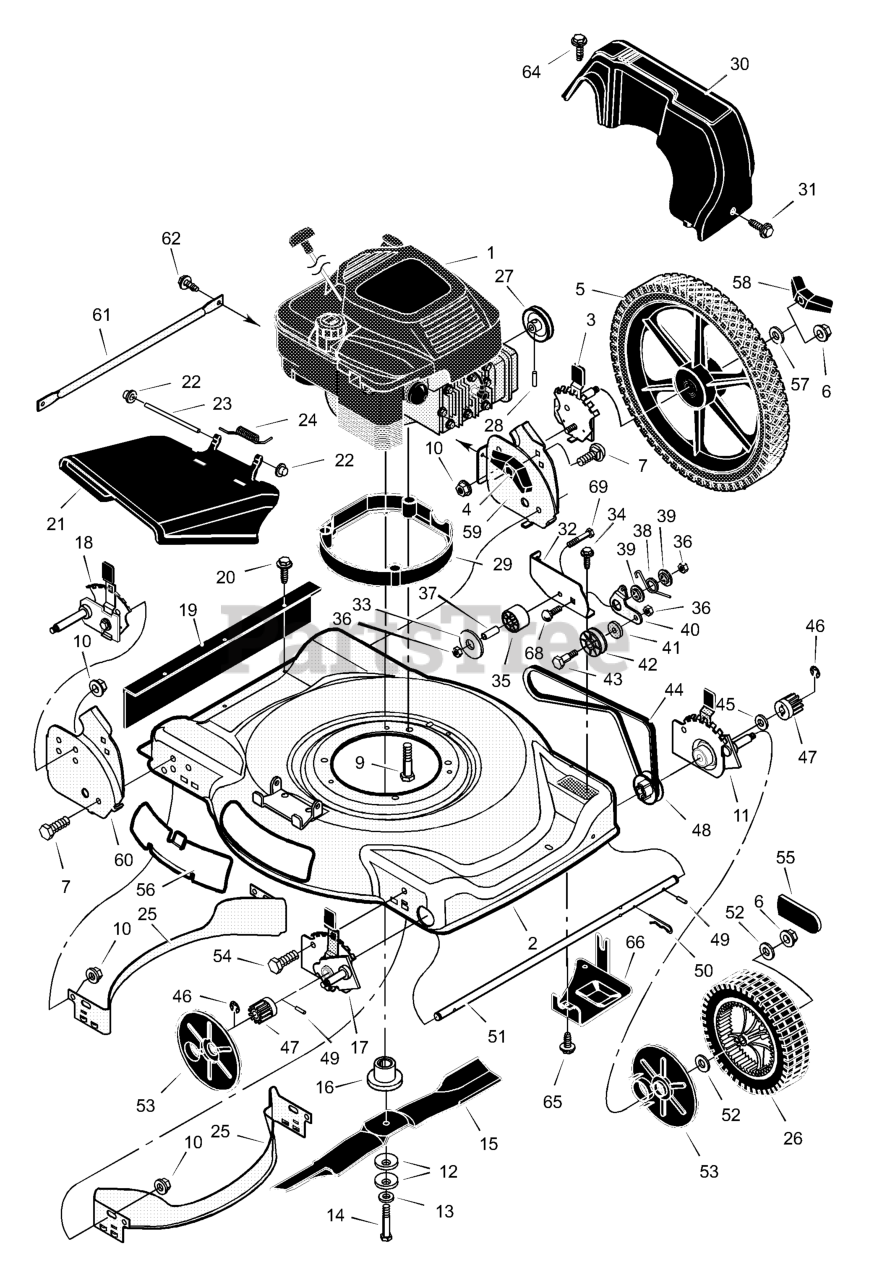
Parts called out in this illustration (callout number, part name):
1	Engine
2	Housing
3	Height Adjuster, Left Rear
5	Wheel and Tire, Rear
6	Locknut, Flange
7	Bolt, Carriage
9	Bolt, Engine
10	Nut
11	Height Adjuster, Left Front
12	Washer, Belleville
14	Bolt, Hex
15	Blade, 3-n-1
16	Adapter, Blade
17	Height, Adjuster, Right Frt.
18	Height, Adjuster, Right Rr.
19	Guard, Rear
21	Deflector, Chute
22	Push-On Cap
23	Pin, Pivot
26	Wheel and Tire, Drive
28	Pin, Spring
29	Base, Engine
30	Cover, Belt (Black)
32	Bracket, Idler Support
33	Washer
34	Screw
35	Idler, Backside
36	Locknut
37	Bearing
40	Arm, Pivot
42	Pulley, Idler
43	Bolt, Shoulder
46	Ring, Retainer
47	Gear, Pinion
49	Pin, Drive
50	Pin, Hair
52	Washer
53	Cover, Dust
54	Bolt
55	Hub Cap
56	Plate, Mulch
58	Knob, Axle
59	Bracket, Left Handle
60	Bracket, Right Handle
66	Shield, Debris
68	Bolt, Carriage
